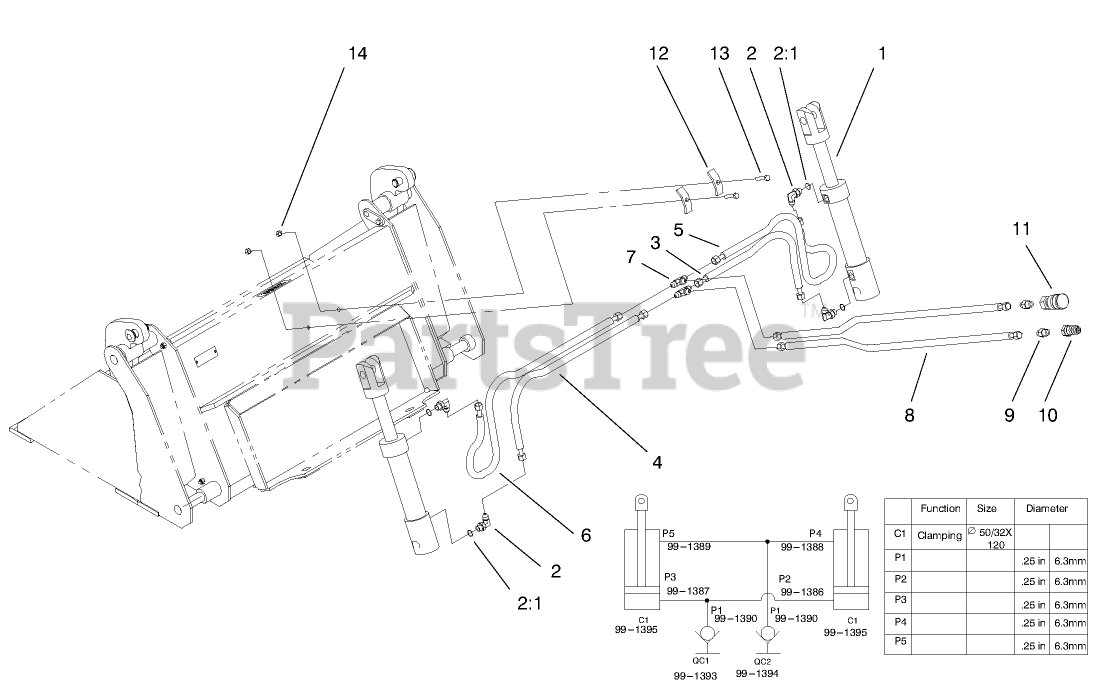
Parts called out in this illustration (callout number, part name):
1	CYLINDER - HYDRAULIC
2	FITTING-ELBOW, 90 DEG
2:1	O-RING
3	HOSE ASM-HYDRAULIC
4	HOSE ASM-HYDRAULIC
5	HOSE ASM-HYDRAULIC
6	HOSE ASM-HYDRAULIC
7	ADAPTER - TEE
8	HOSE ASM-HYDRAULIC
9	ADAPTOR,HYDRAULIC
10	QUICK COUPLER - MALE
11	QUICK COUPLER-FEMALE
12	CLAMP - HOSE
13	SCREW-HHF
14	NUT-LOCK, NI
